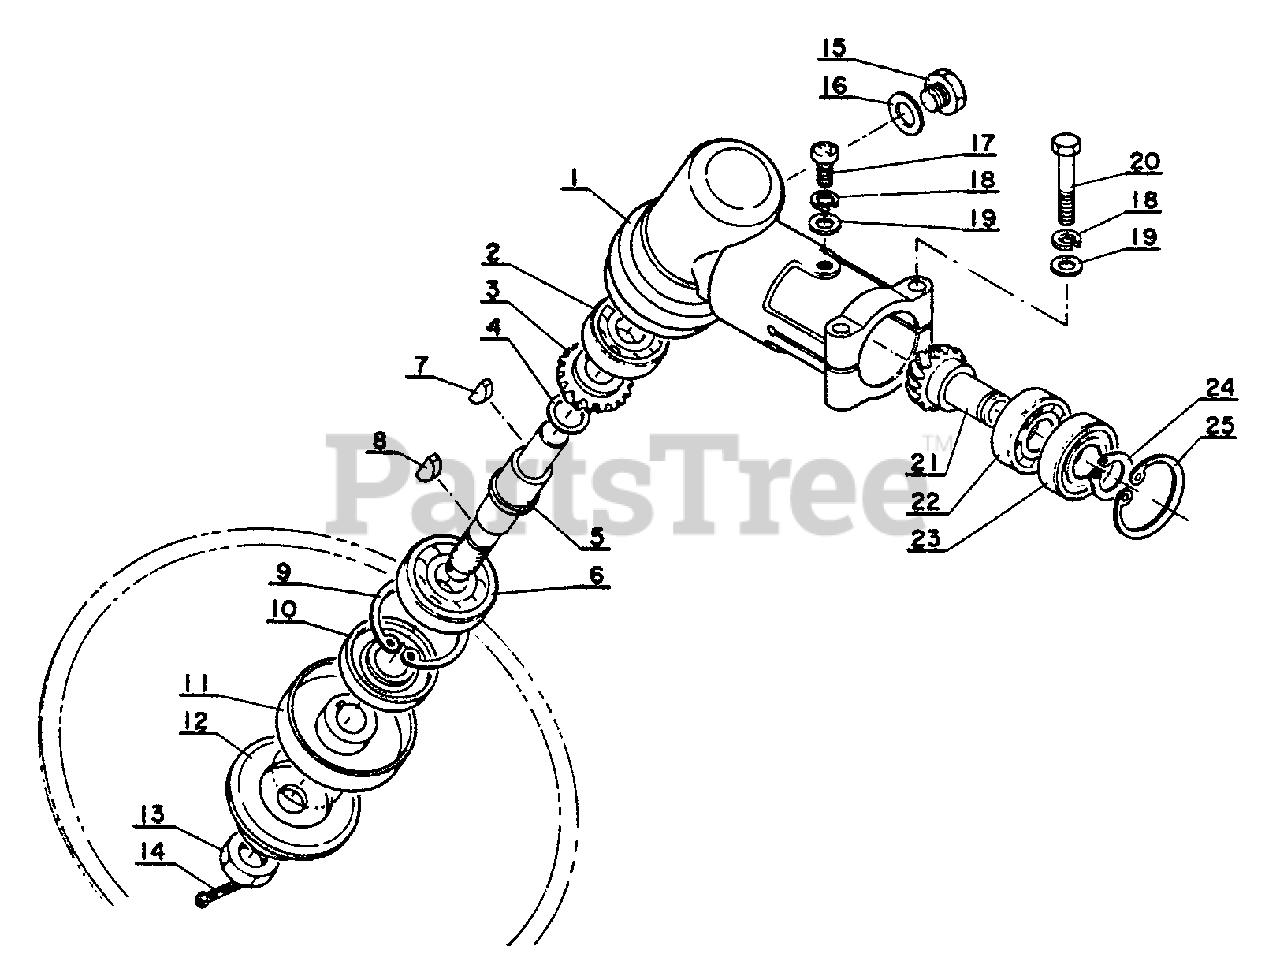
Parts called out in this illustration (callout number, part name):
1	CASE, GEAR
2	BEARING, BALL - 6000
3	GEAR SET
4	WASHER
5	DRIVESHAFT
6	BEARING, BALL - 6201
9	RING, RETAINING - 32
10	SEAL, OIL
11	ADAPTOR, BLADE - UPPER
12	ADAPTOR, BLADE - LOWER
13	NUT - 10 -- LEFT HAND
14	PIN, SPLIT - 2X22
15	BOLT - 8X8
16	GASKET
17	SCREW - 5X10
18	LOCKWASHER - 5
19	WASHER - 5
20	BOLT - 5X30
21	GEAR SET
22	BEARING, BALL - 6001
23	BEARING, BALL - 6001
24	RING, RETAINING - 12
25	RING, RETAINING - 28
